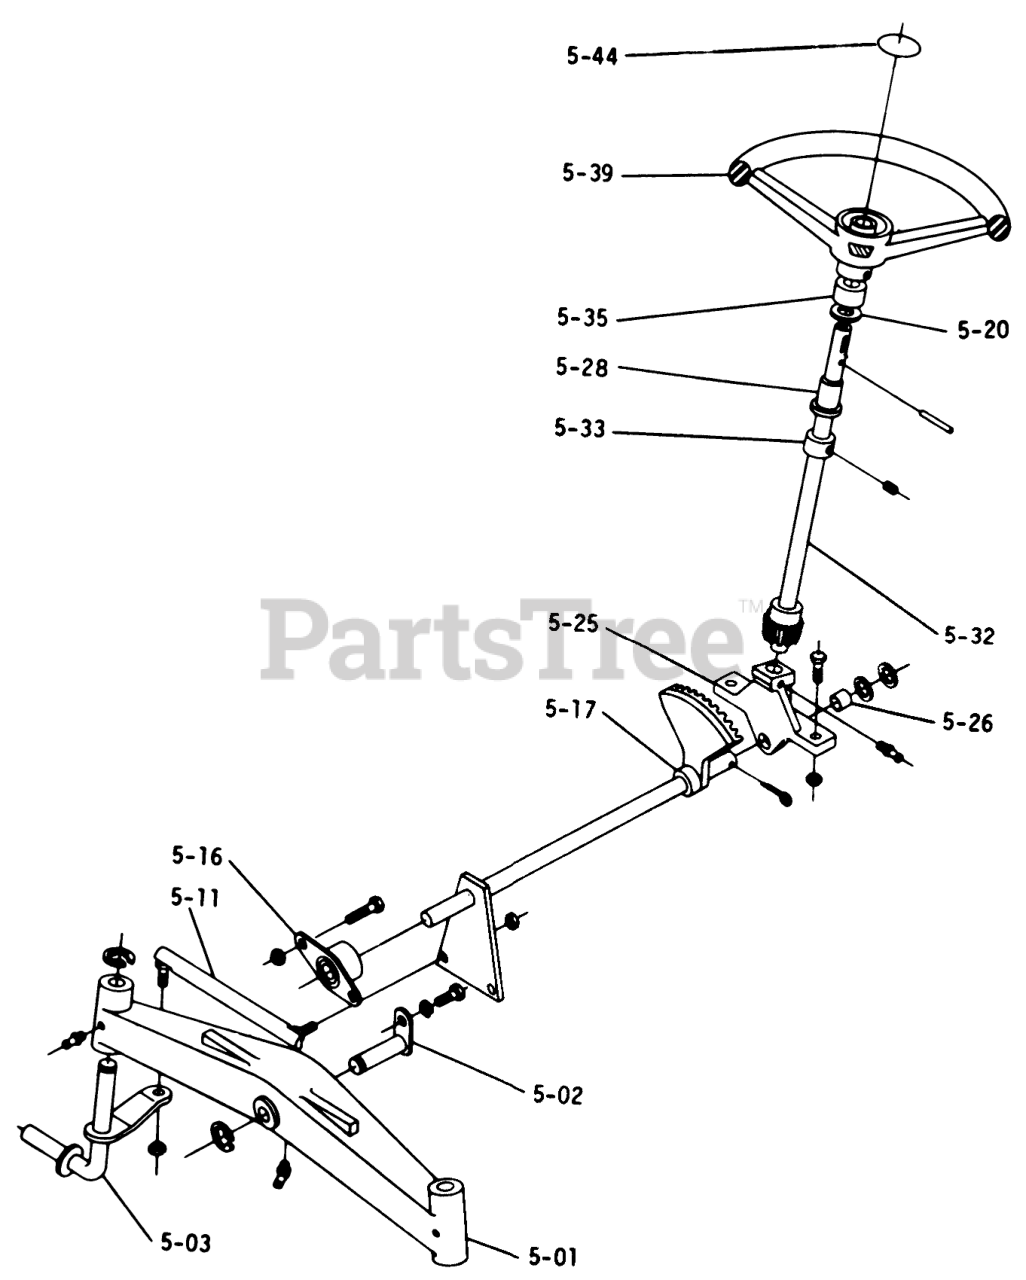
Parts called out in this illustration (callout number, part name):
5-01	AXLE-FRONT
5-02	PIN AND PLATE ASM
5-03	R.H. Spindle
5-11	Tie Rod RH
5-16	BEARING-FLANGED
5-17	Lower Steering Shaft Assembly
5-20	WASHER-BOWED
5-25	Support
5-26	BEARING-BRONZE
5-28	BEARING
5-32	Upper Steering Shaft
5-33	Collar
5-35	Collar
5-39	STEERING WH 13" SOFT
5-44	STEERING WHEEL INSE
